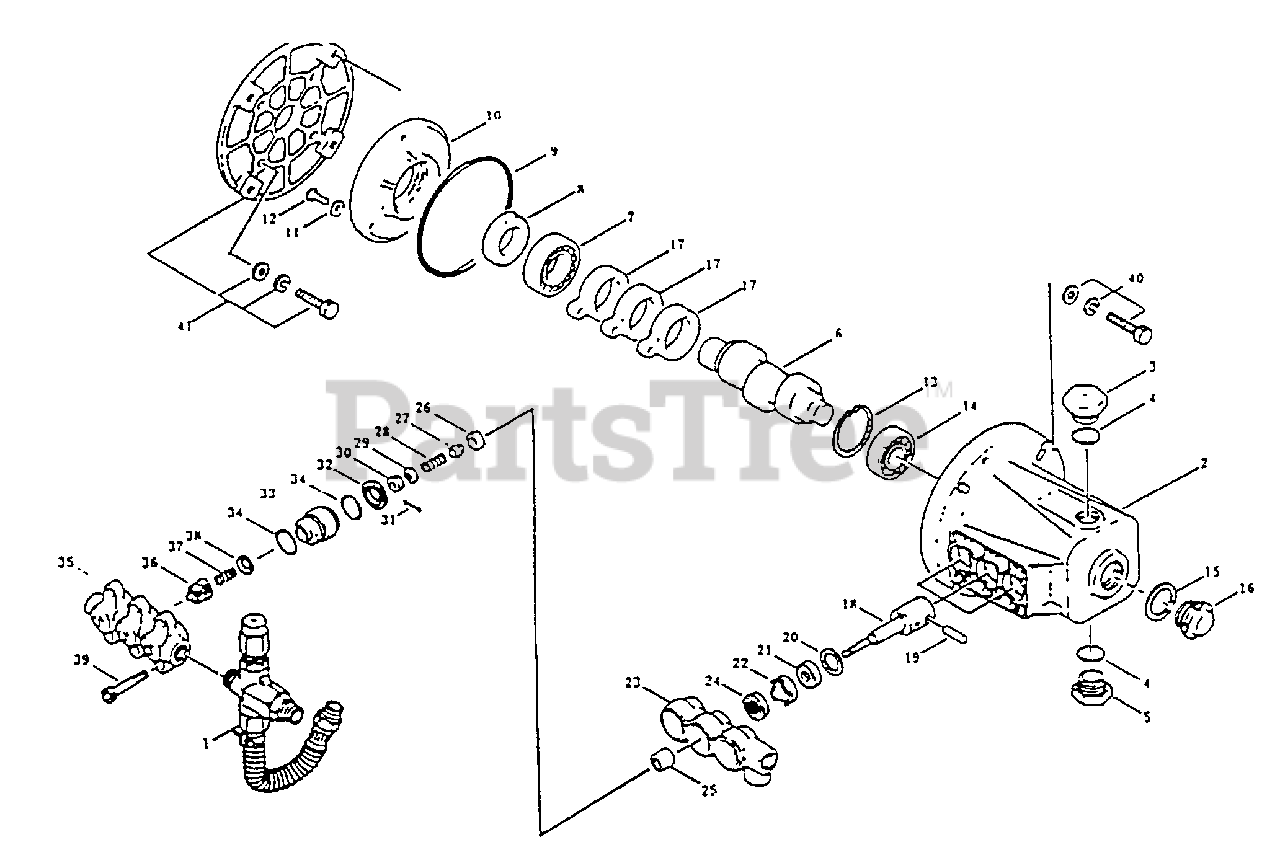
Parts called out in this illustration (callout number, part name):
1	Regulating Unloader
2	Crankcase
3	Oil Filter Cap
4	O-Ring
5	Drain Plug - 1/2" NPT
6	Crankshaft - 3450 RPM
7	Bearing - Inner
8	Oil Seal
9	O-Ring, Bearing Case
10	Bearing Case - Inner
11	Seal Washer (M6)
12	Phil. Head Screw (M6 x 16)
13	Retaining Ring
14	Bearing Outer -
15	Flat Flex, Gasket, Oil Gauge
16	Bubble Oil Guage
17	Connecting Rod "H"
18	Piston Rod - Unchromed
19	Piston Rod Pin
20	Washer
21	Oil Seal
22	Seal Retainer
23	Inlet Manifold
24	Lo-Pressure Seal
25	Ceramic Plunger
26	Inlet Valve
27	Spacer
28	Inlet Valve Spring
29	Conical Washer - (M6)
30	Nut (M6)
31	Cotter Pin
32	Hi-Pressure Seal
33	Discharge Adapter Seat
34	O-Ring Adapter
35	Discharge Manifold
36	Valve Spring Retainer
37	Discharge Valve Spring
38	Discharge Valve
39	Hex Socket Head Screw (M8 x 75. Dschg. Mlld.)
40	Bolt Mount Kit
41	Adapter Mount Kit - Gas
